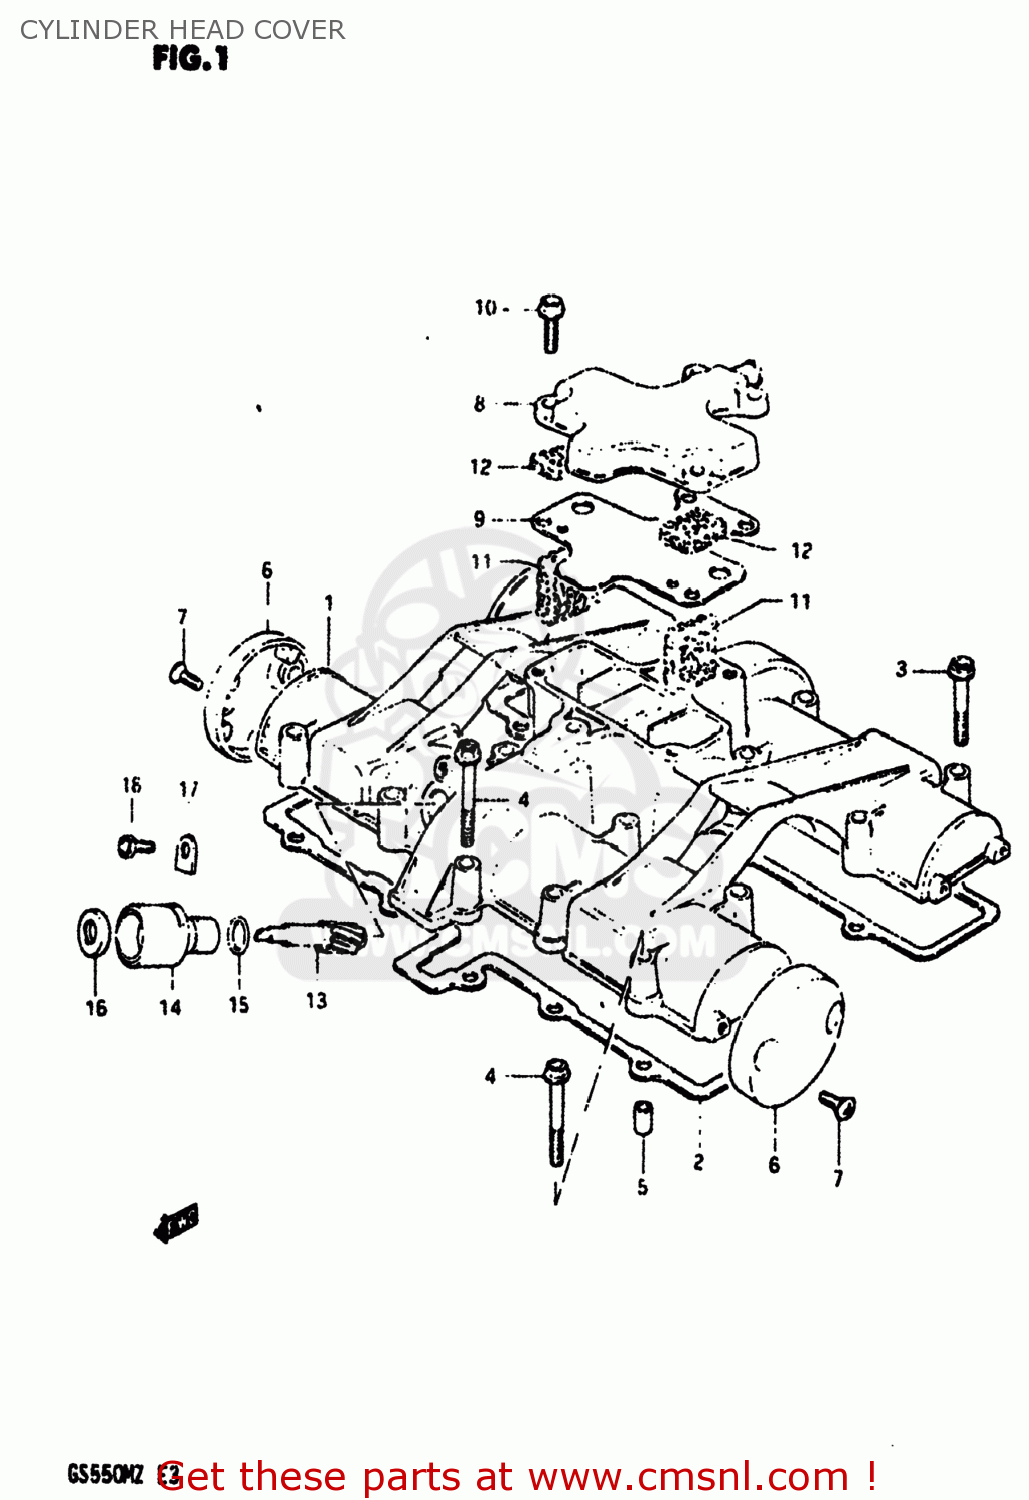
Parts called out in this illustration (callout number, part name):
1	COVER,CYLINDER HEAD
2	GASKET,CYLINDER HEAD COVER (MCA)
3	BOLT
4	BOLT,UNDER
5	PIN(6.2X8X11)
6	CAP,CYLINDER HEAD COVER
7	SCREW(5X12)
8	COVER,BREATHER
9	GASKET (MCA)
10	BOLT,REAR
11	COVER,BREATHER
12	SEPARATOR,OIL BREATHER
13	GEAR,TACHOMETER DRIVEN
14	SLEEVE,TACHOMETER DRIVE
15	SEAL,TACHOMETER DRIVEN
16	SEAL,OIL(5X12X8)
17	PLATE,TACH DRIVE GEAR SLEEVE
18	SCREW(5X12)
